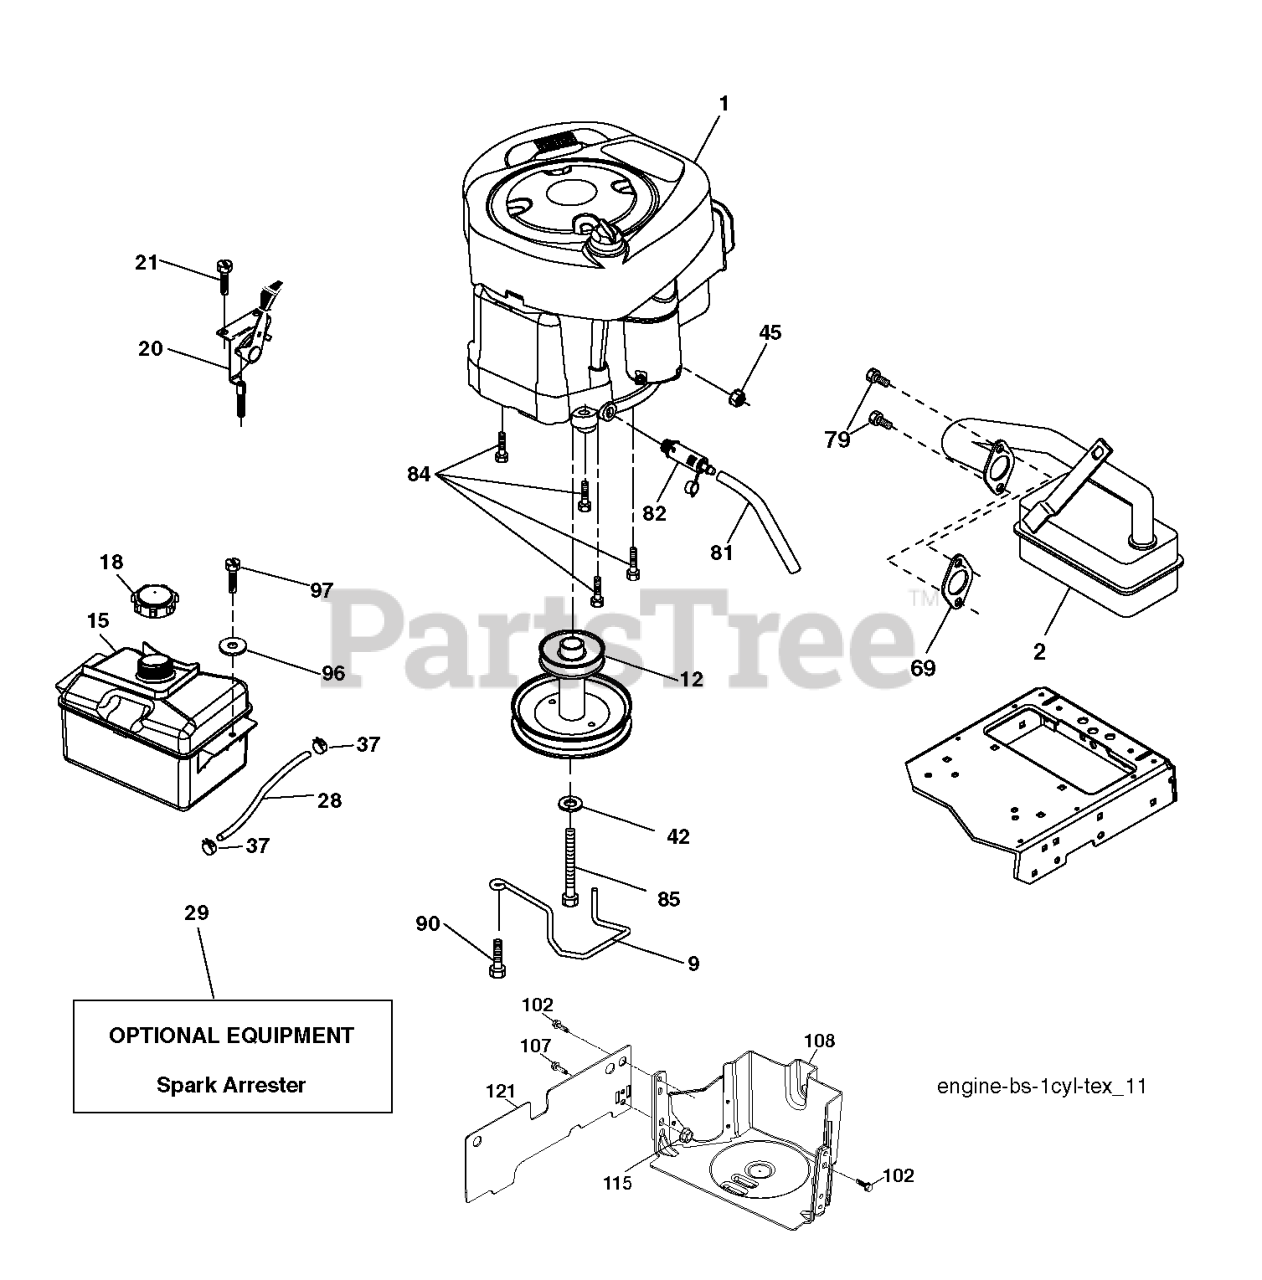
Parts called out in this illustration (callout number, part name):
2	MUFFLER.B&S.MODEL.21.11HP.OHV
9	KEEPER.BELT.ENGINE.3.25 (3 2)
12	PULLEY.ENG.CL.MECH.SLVR.LT/YT
15	RP TANK FUEL FRT 1.5 GAL
18	FUEL CAP
20	CONTROL.TH/CK.C.
21	SCREW.#10 X 0.750.BOS
28	LINE.FUEL.20
29	KIT.SPARK ARRESTOR 794945 B&S
37	HOSE CLAMP
42	LOCKWASHER
45	NUT
69	REPL BY 532 27 22-93
79	SCREW.SOCKET HD.5/16-1
81	TUBE, DRAIN OIL ASM.
82	PLUG DRAIN OIL EASY
84	SCREW.3/8-16
85	BOLT HEX 7/16-20X4-1/4"
90	SCREW 3/8-16X1
97	SCREW HEXWSHR 1/4-20X3/4
102	SCREW
107	SCREW.1/4-20X5/8
108	COVER PULLEY
115	PALNUT 1/4
121	SHIELD LEFT
